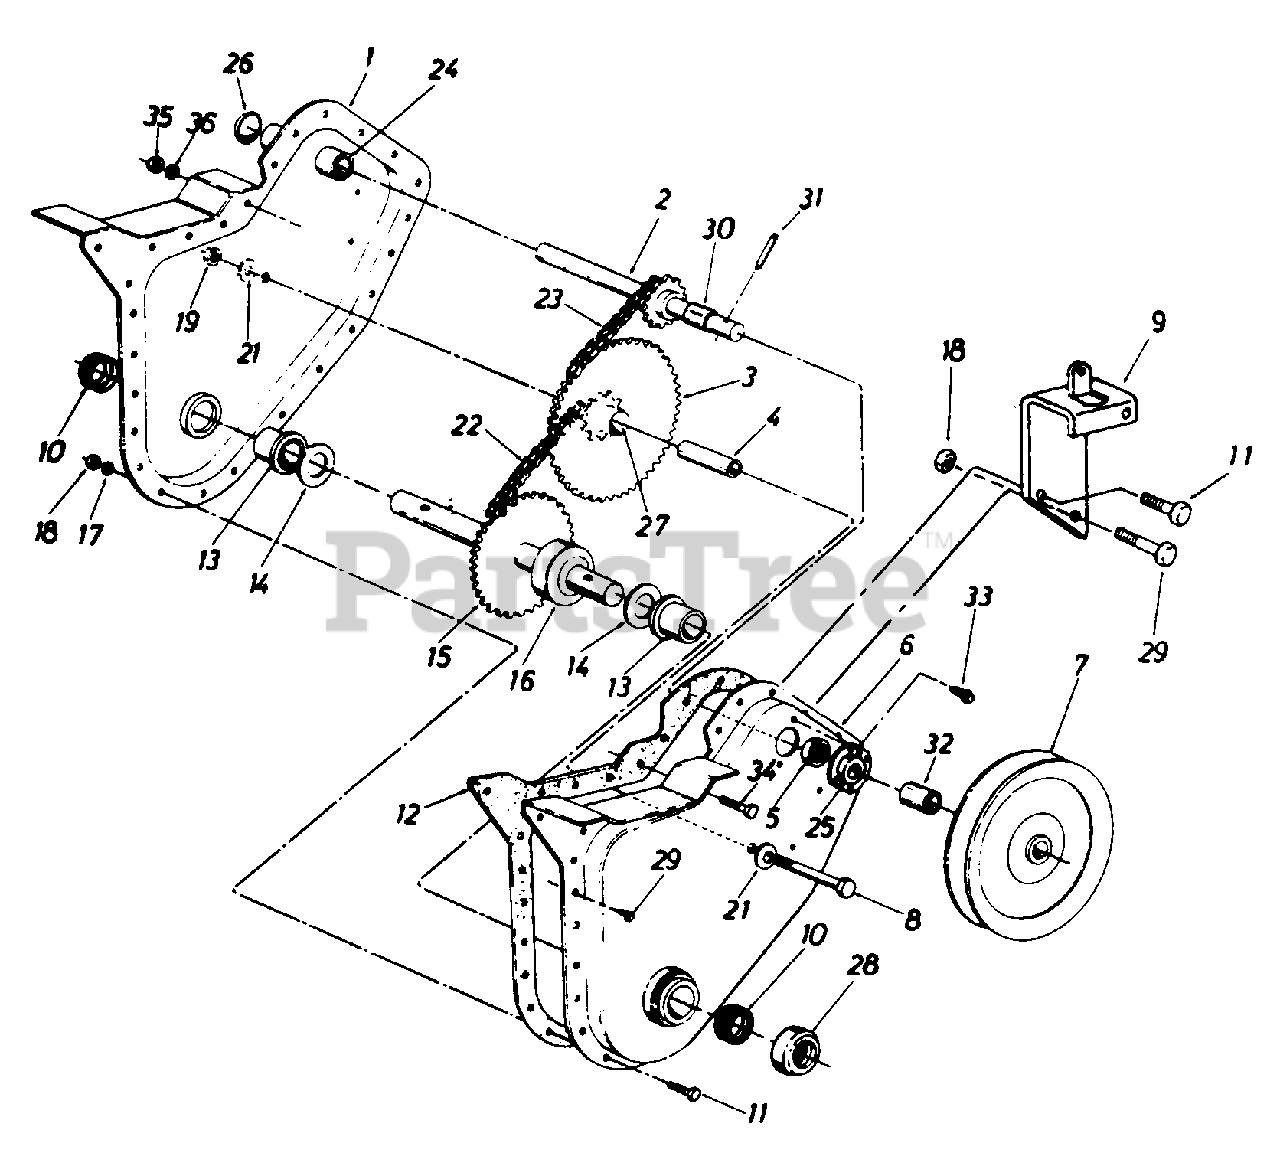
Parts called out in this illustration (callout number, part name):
1	Chain Case Ass'y. R.H.
2	Input Shaft Ass'y.
3	Hub and Sprocket Ass'y.
4	Bearing Inner Race
5	Ball Bearing
6	Chain Case Ass'y. L.H.
7	Pulley Chain Case
8	Hex Bolt 3/8-24 x 2.51'
9	Fuel Tank Brkt.
11	Hex Bolt 1/4-28 x .625
12	Gasket
13	Flange Brg. .879" I.D.
14	Fl-Wash. .88" I.D. x 1.5
15	Tine Shaft Ass'y.
16	Spacer 7/8" I.D.
17	L-Wash. 1/4" I.D.
18	Hex Nut l/4-28 Thd.
19	Hex Ins. L-Nut 3/8-24 Thd.
21	Bell-Wash. .406" I.D.
22	Chain #4201/2" Pitch 38 Links
23	Chain #35 .375" Pitch 50 Links
24	Bearing .62" I.D. x .813"
25	Bearing Housing
26	Expansion Plug 13/16" Dia.
27	Bearing
28	Dust Cap
29	Hex Wash. Hd. Self-Tap Scr. 1/4-20 x .50" Lg.
30	Spacer.63" I.D. x .77" O.D. x .38" Lg.
31	Spring Pin Spiral 1/4" Dia. X 1 1/2" Lg.
32	Spacer .647 x 1.25
33	Hex Wash. Hd. Self-Tap Scr. 1/4-20 x .38" Lg.
34	Hex Bolt 5/16-18 x .75"
35	Hex Nut 5/16-18 Thd.
36	L-Wash. 5/16" I.D.
